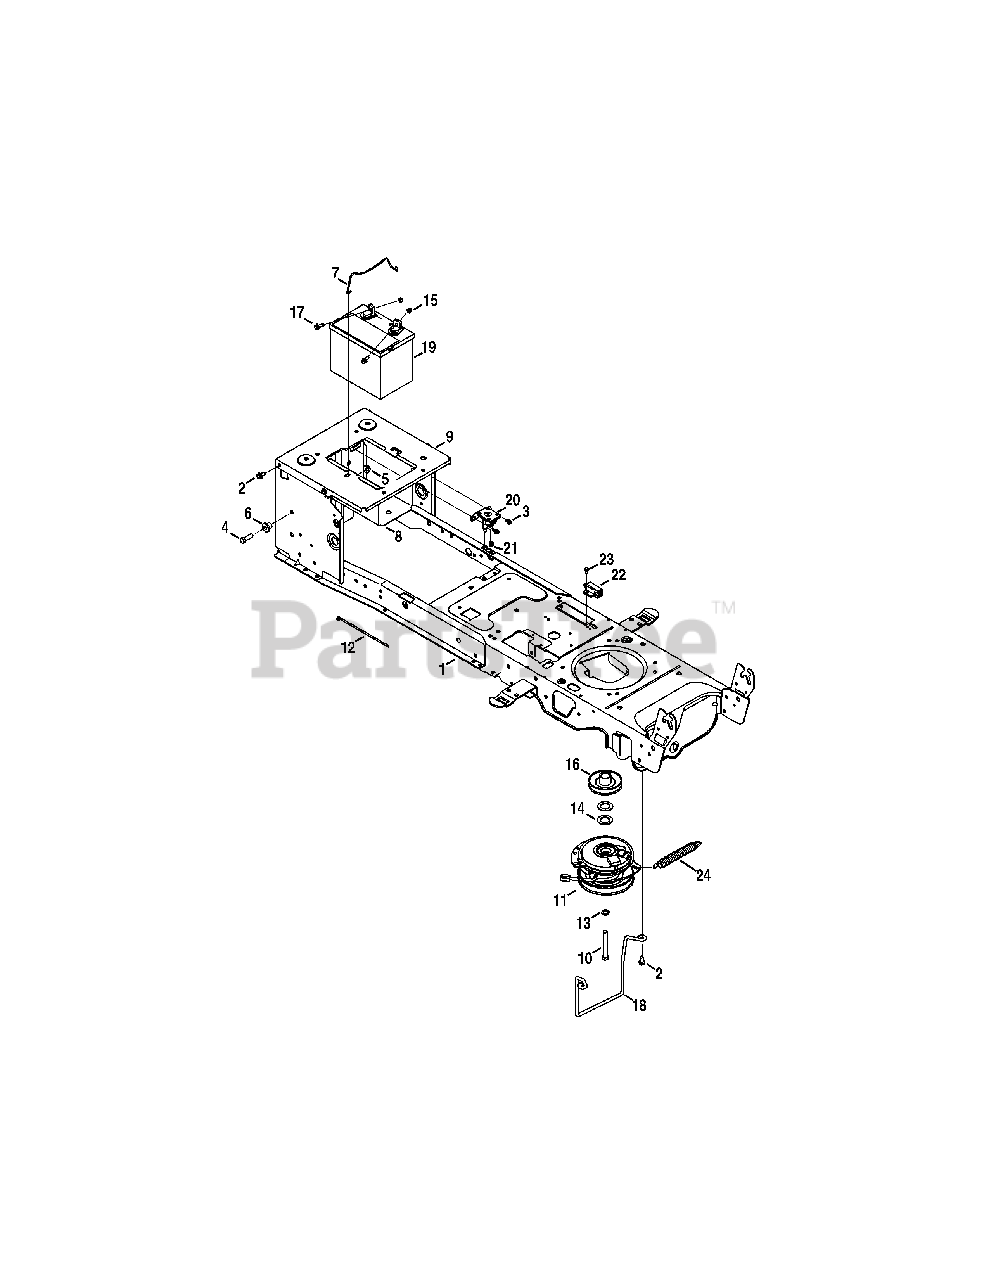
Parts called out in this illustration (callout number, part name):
1	Frame
2	Taptite Screw, Indented Washer, 5/16-18:.750
3	Taptite Screw, Indented Washer, 1/4-20:0.375
4	Hex Head Screw, 3/8-16:1.25
5	Flangelock Nut, 3/8-16
6	Shoulder Spacer, .38 X 1.0 X .70
7	Battery Holder Rod
8	Battery Tray
9	Seat Frame Bracket
10	Hex Head Screw, 7/16-20:3.50
11	Electric PTO Clutch
12	Cable Tie, 3/16 x .05 x 7.4
13	Lock Washer, 7/16
14	Flat Washer, 1.031 x 1.620 x .095
15	Sems Nut, 1/4-20
16	Electric PTO Engine Pulley
17	Hex Head Flange, 1/4-20:.75
18	Belt Guard
19	Battery, Sears 725-05088
20	Solenoid, 12 V
21	Flangelock Nut, 1/4-20
22	Interlock Switch
23	Shoulder Screw, #10-32:.500
24	Extension Spring, .56 Od. x 5.52 Lg.
